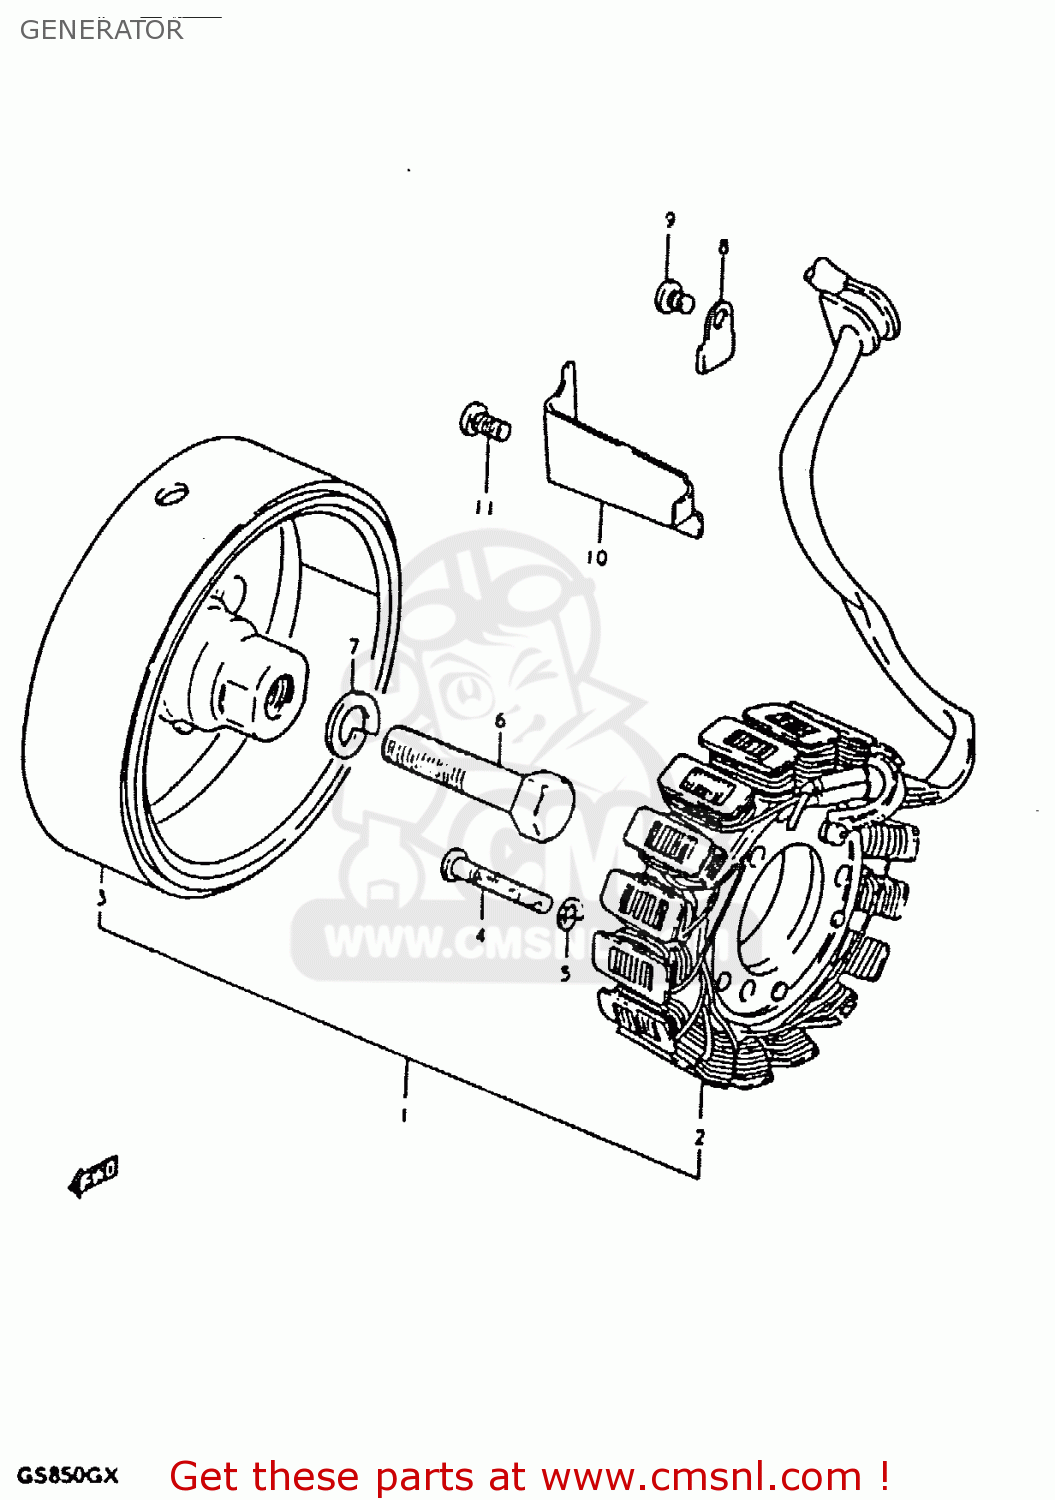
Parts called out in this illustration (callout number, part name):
1	GENERATOR ASSEMBLY
2	STATOR ASSEMBLY
3	ROTOR ASSEMBLY
4	SCREW
5	LOCK WASHER
6	BOLT 12X45
7	WASHER,LOCK 12
8	CLAMP,GENERATOR LEAD WIRE
9	SCREW
10	CLAMP,GENERATOR LEAD WIRE
11	SCREW
